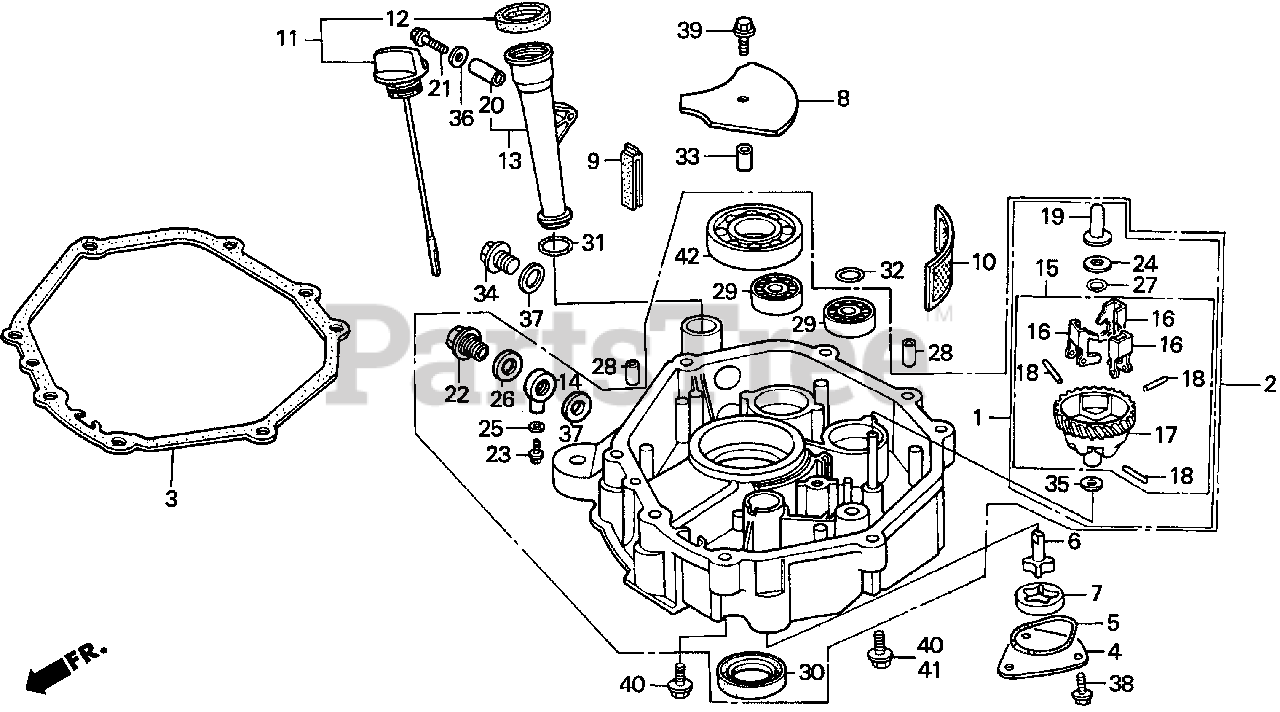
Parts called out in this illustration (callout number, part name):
1	GOVERNOR KIT Use from Engine SN 2086153.
1	GOVERNOR KIT Use up to Engine SN 2086152.
2	PAN ASSY., OIL (NOT AVAILABLE)
2	PAN ASSY., OIL
3	GASKET, OIL PAN
4	COVER, OIL PUMP
5	O-RING, PUMP COVER
6	ROTOR (INNER)
7	ROTOR, OIL PUMP (OUTER)
8	PLATE, OIL FILTER
9	RUBBER, OIL RETURN
10	SCREEN, OIL FILTER
11	CAP ASSY., OIL FILLER
12	GASKET, OIL FILLER CAP
13	EXTENSION, OIL FILLER
14	JOINT, OIL DRAIN
15	GOVERNOR ASSY.
16	WEIGHT, GOVERNOR
17	HOLDER, GOVERNOR WEIGHT
18	PIN, GOVERNOR WEIGHT
19	SLIDER, GOVERNOR
20	COLLAR, EXTENSION Use up to Engine SN 1257294.
21	BOLT, HEAD COVER
22	BOLT, OIL JOINT
23	BOLT, DRAIN PLUG
24	WASHER (6X16)
25	WASHER, DRAIN PLUG (10.2MM)
26	WASHER, OIL DRAIN (24MM)
27	CLIP, GOVERNOR HOLDER
28	PIN, DOWEL (8X12)
28	PIN A, DOWEL (8X12)
29	BEARING, RADIAL BALL (6202)
30	OIL SEAL (35X52X8)
31	O-RING (22.5X2.2) Use from Engine SN 1257295.
32	O-RING (11.8X2.4)
33	COLLAR, OIL FILTER SETTING
35	WASHER, PLAIN (6MM)
36	WASHER, PLAIN (6MM)
37	WASHER, DRAIN PLUG (20MM)
38	BOLT, FLANGE (6X12) Use up to Engine SN 1543277.
39	BOLT, FLANGE (6X25)
40	BOLT, FLANGE (8X40)
41	BOLT, FLANGE (8X60)
42	BEARING, RADIAL BALL (6207)
